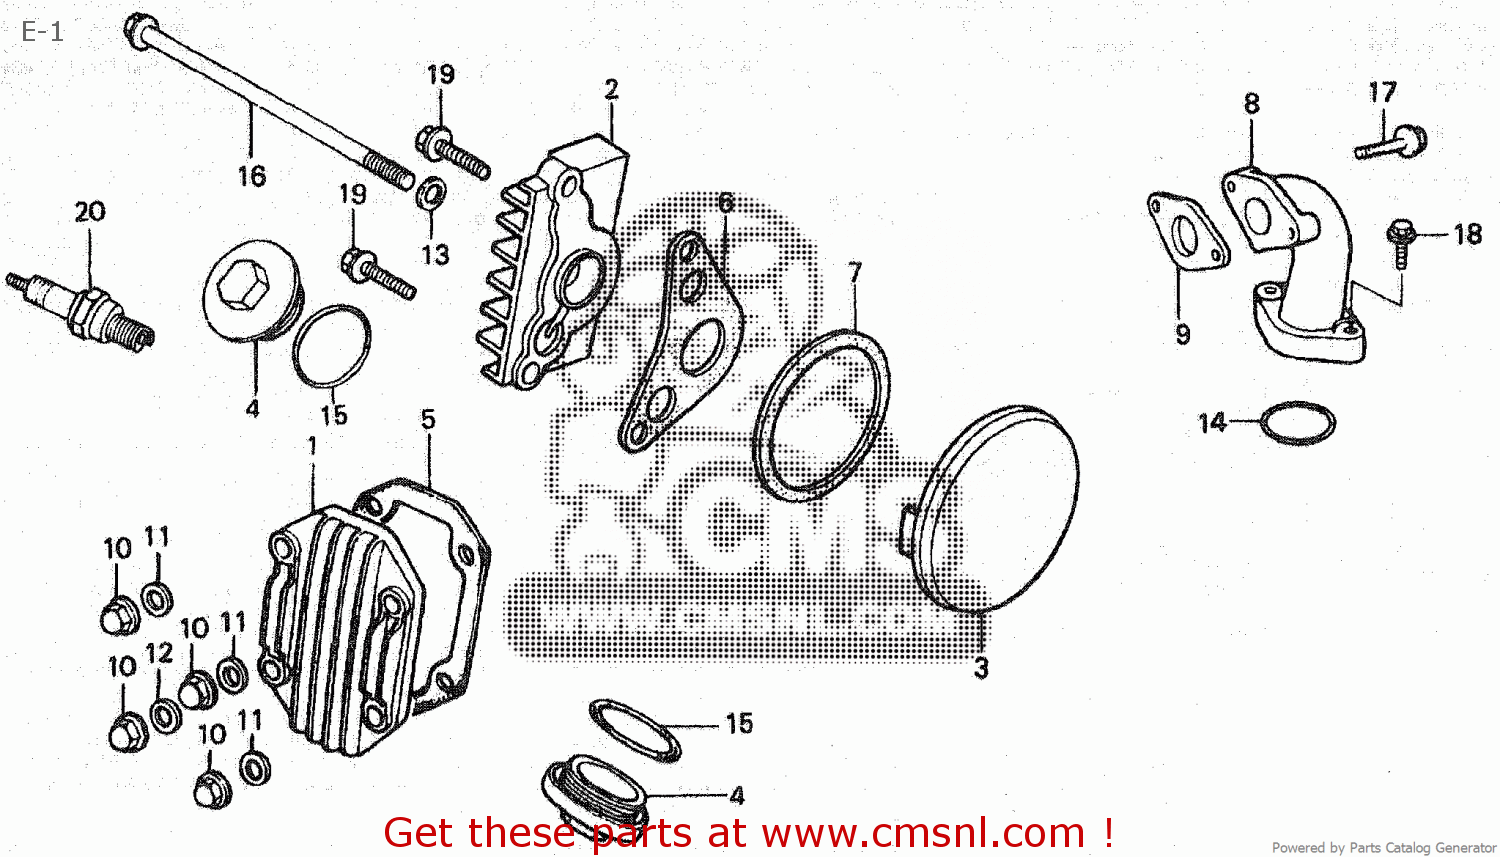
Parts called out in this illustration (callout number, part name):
1	COV,CYLN HEAD
2	COVER,R.CYLN.HEAD
3	COV,L,HEAD SIDE
4	CAP, TAPPET
5	GSKT,CYLIN.HEAD (MCA)
6	GSKT,CYLN.HEAD R (NAS)
7	GSKT,HEAD,COVER (NAS)
8	PIPE,IN.
9	GSKT INLET PIPE
10	NUT CAP 7MM
11	WASHER,SEALING,7M
12	WASHER,A SEALING
13	WASHER, 12MM
14	O-RING,27X2.0
15	O RING, 30.8M/M
16	BOLT,FLANGE,6X110
17	BOLT,FLANGE,6X22
18	BOLT,FLANGE,6X25
19	BOLT FLANG 6X20
20	SPARK PLUG(CR6HSA
